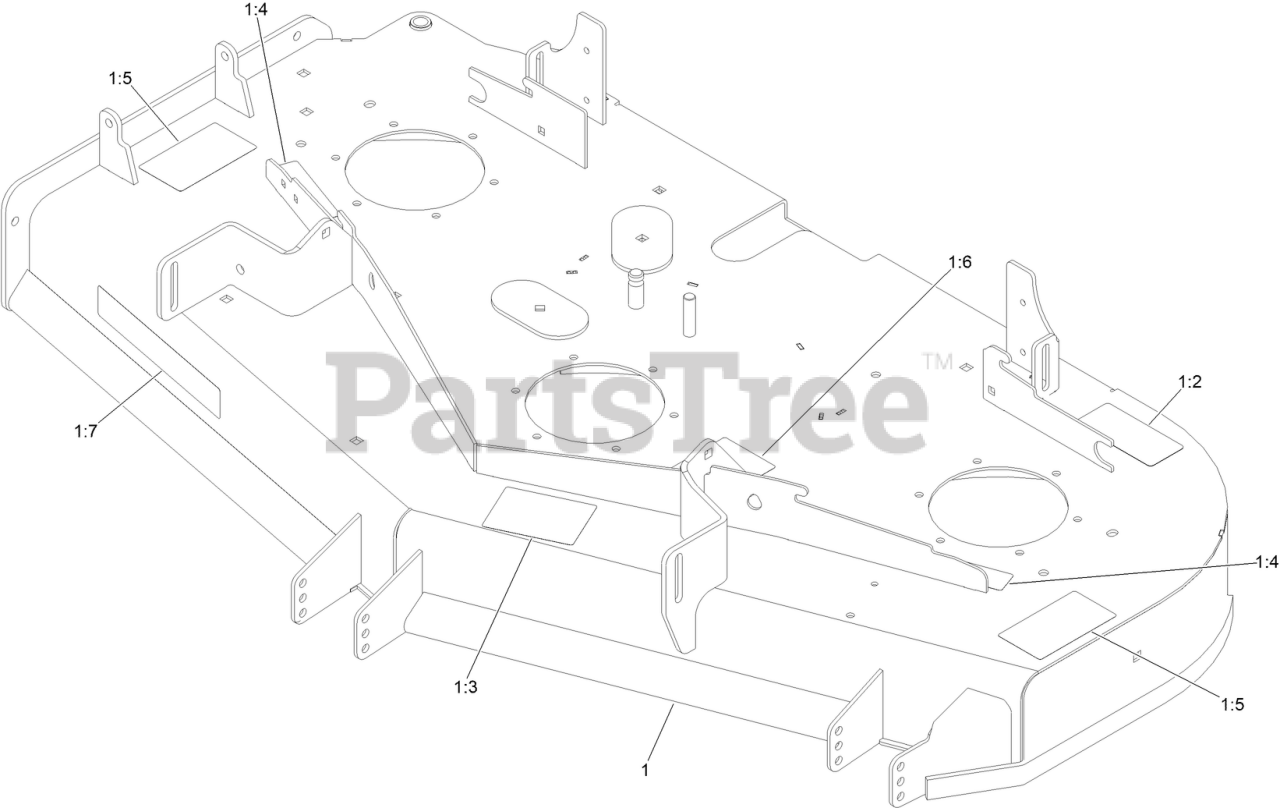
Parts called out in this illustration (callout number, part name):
1	DECK DECAL ASM
1:2	DECAL-TORQUE, BLADE BOLT
1:3	DECAL-SCALP, ANTI
1:4	DECAL-COVER, MISSING
1:5	DECAL-DANGER
1:6	DECAL-ROUTING, BELT
